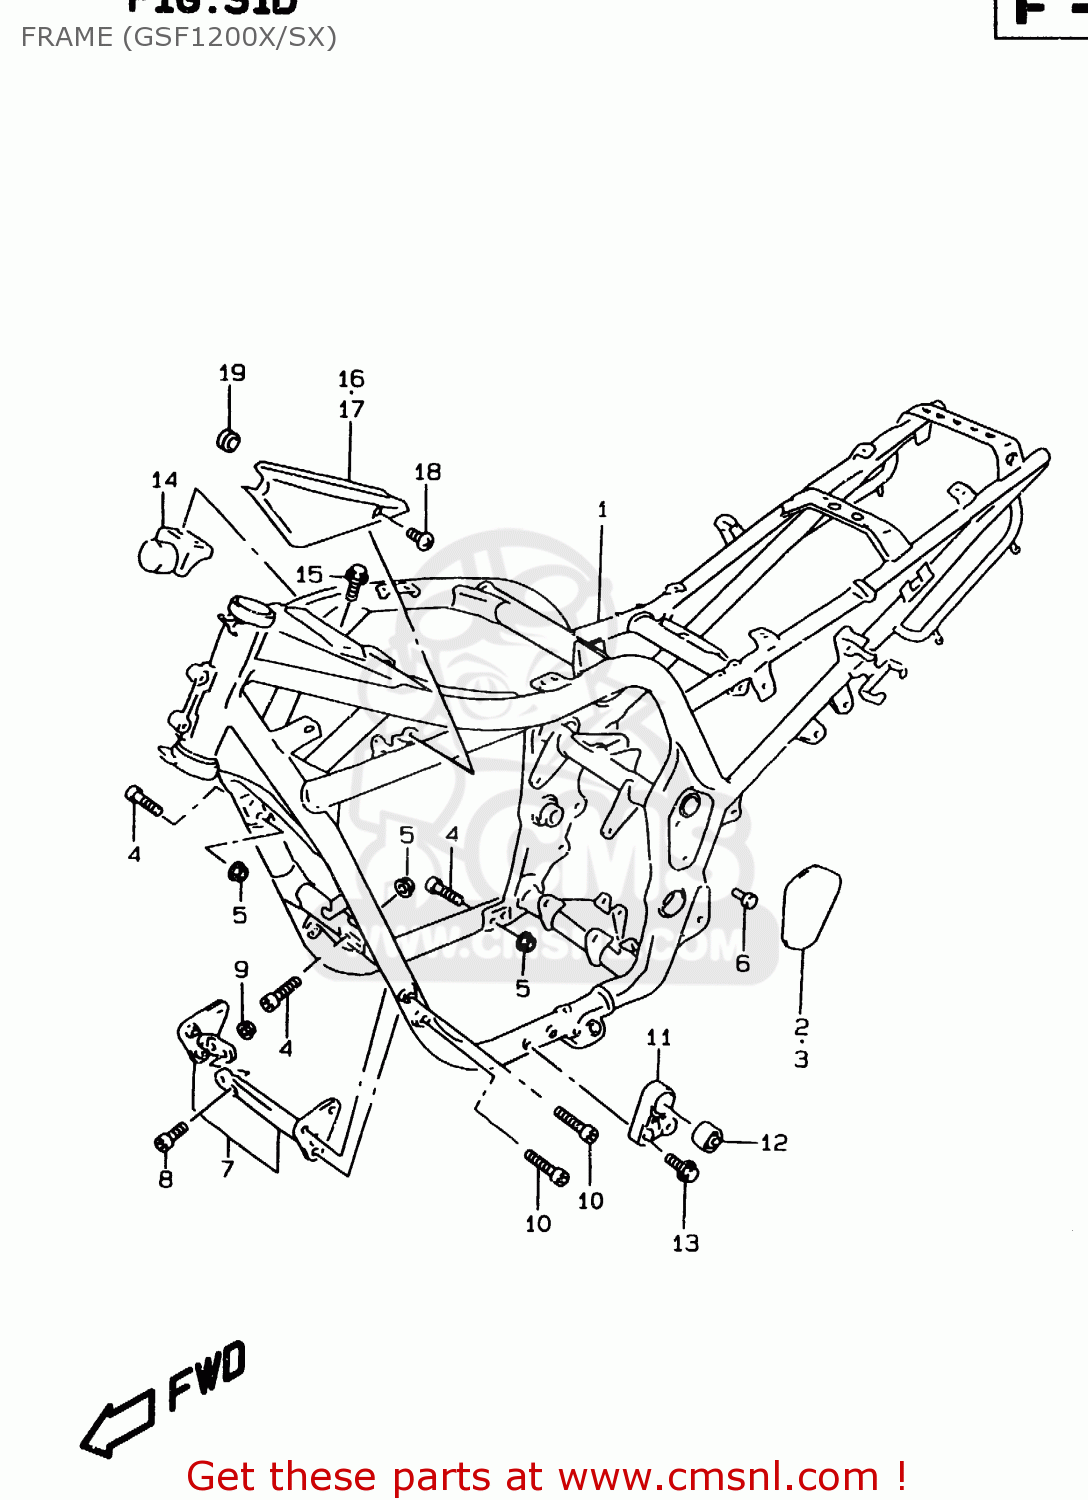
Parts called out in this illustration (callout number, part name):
1	FRAME(BLACK)
2	COVER,FRAME BODY,R
3	COVER,FRAME BODY,L
4	BOLT(10X33)
5	NUT
6	CLIP
7	PLATE ASSEMBLY,ENGINE MOUNT
8	BOLT
9	NUT
10	BOLT
11	BRACKET,ENGINE MOUNTING NO.2
12	BUSH,ENG MOUNTING NO.2
13	BOLT
14	DAMPER COMP,FRAME
15	BOLT
16	COVER,FRAME HEAD,R
17	COVER,FRAME HEAD,L
18	SCREW(5X12)
19	CUSHION
